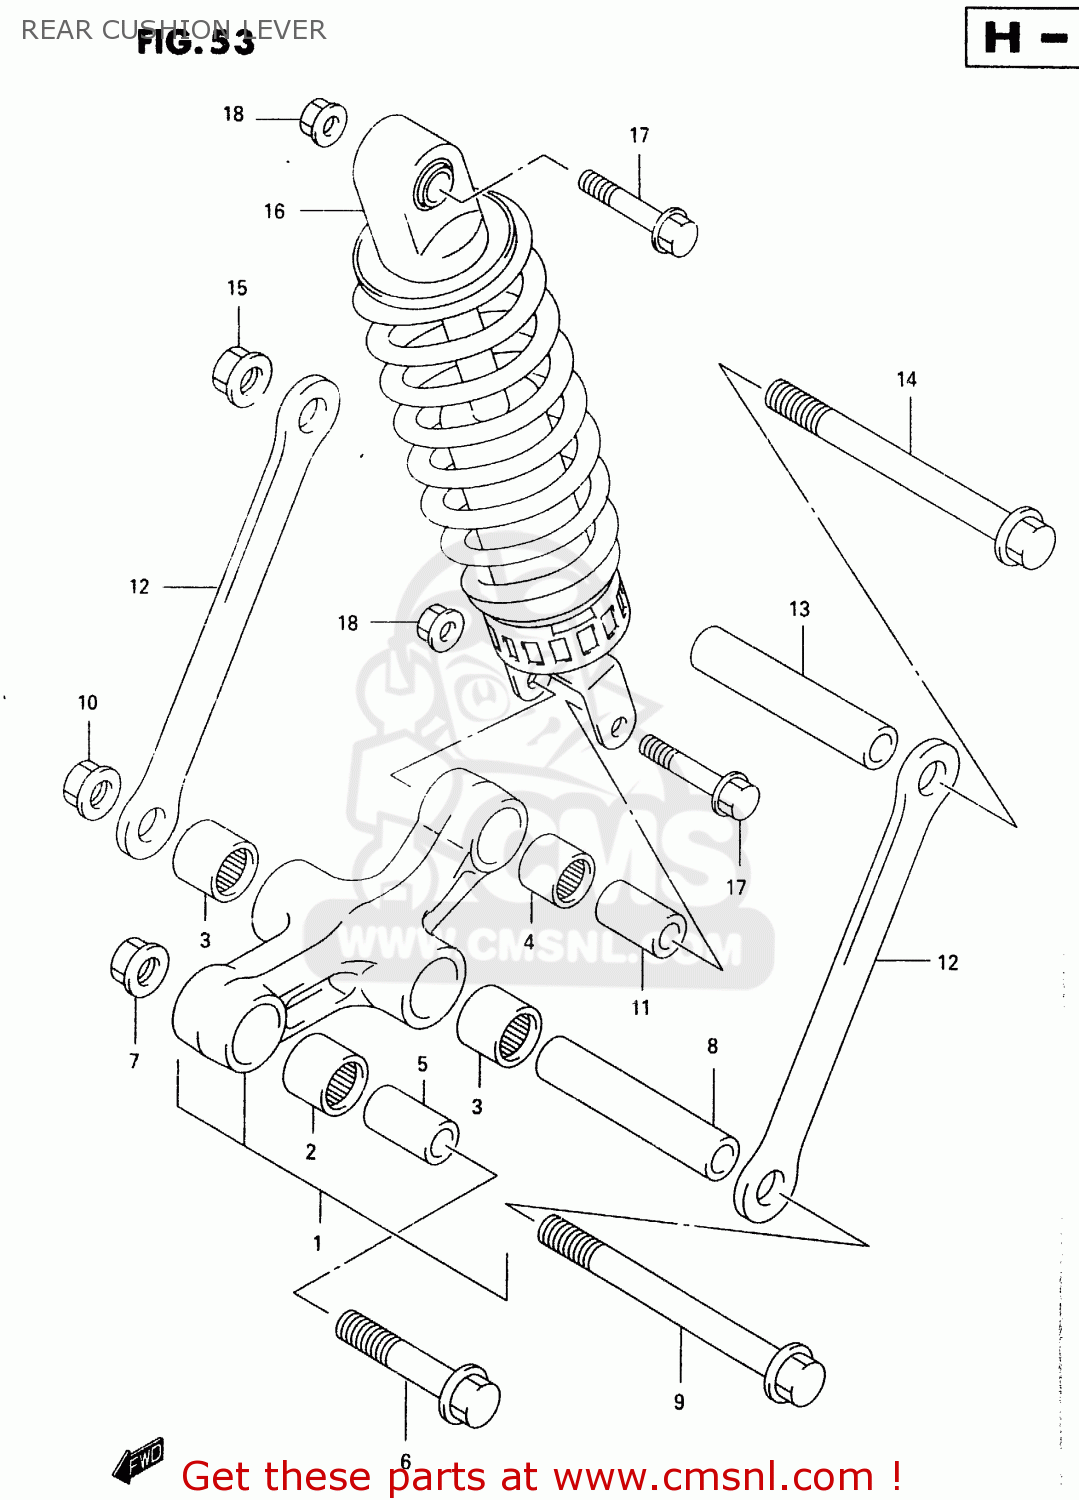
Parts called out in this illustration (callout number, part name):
1	LEVER SET,RR CUSHION
2	BEARING(20X27X30)
3	BEARING(20X27X23.5)
4	BEARING(17X24X26)
5	SPACER(14X20X34)
6	BOLT(14X62)
7	NUT
8	SPACER,RR CUSHION ROD
9	SHAFT,RR CUSHION ROD
10	NUT
11	SPACER,RR CUSHION LEVER
12	ROD,RR CUSHION
13	SPACER,RR CUSHION ROD
14	SHAFT,RR CUSHION ROD
15	NUT
16	ABSORBER ASSY,RR SHOCK
17	BOLT(10X52)
18	NUT
